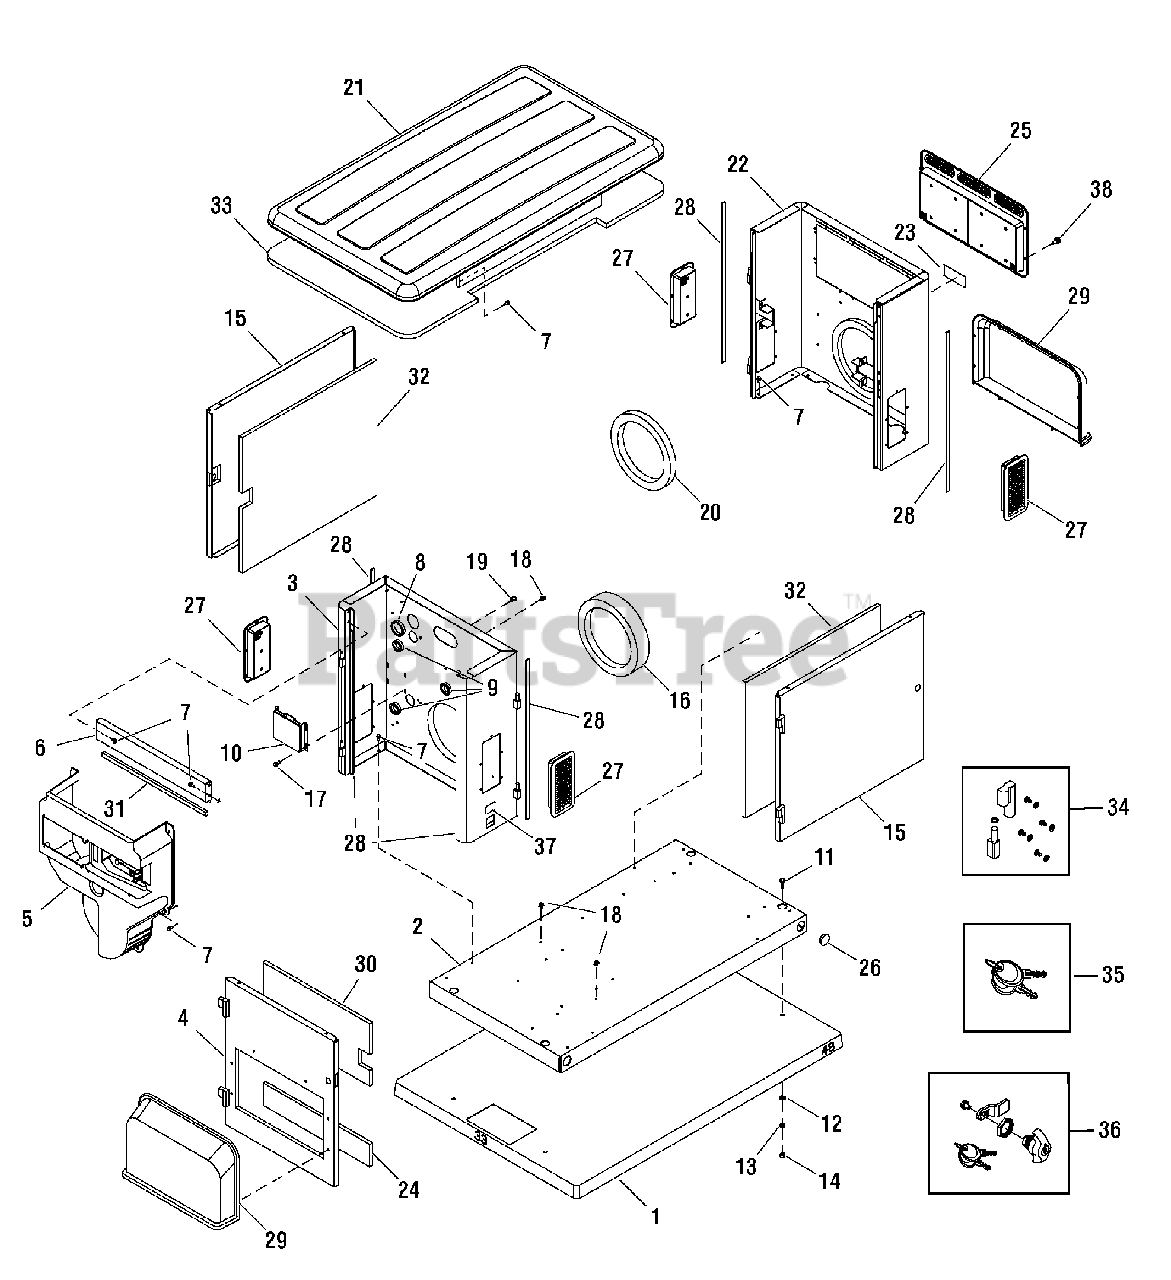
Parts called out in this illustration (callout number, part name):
1	PAD, Mounting w/ Holes
2	BASE, Mounting
3	BULKHEAD ASSEMBLY, Engine End
4	DOOR ASSEMBLY, Engine
5	DUCT ASSEMBLY, Engine
6	SUPPORT RAIL ASSEMBLY
7	BOLT
9	BUSHING, Snap, 1-1/2
10	REGULATOR, Voltage
11	* CAPSCREW, Hex Head, 3/8-16 x 1
12	* WASHER, Flat, 3/8-M10
13	* WASHER, Lock, 3/8
14	* NUT, 3/8-16
16	SEAL, Foam, Engine Air
18	MOUNT, Tie Wrap
20	SEAL, Foam, Alternator Inlet
22	BULKHEAD, Alternator
23	DECAL, Caution Hot Muffler
24	INSULATION, Engine Door, Bottom
25	ASSEMBLY, Vent, Exhaust
29	COVER, Air Intake, Engine
30	INSULATION, Engine Door, Top
32	INSULATION, Front / Rear Door
33	INSULATION, Roof
34	KIT, Door, Hinge
37	DOOR
37	WELDMENT
37	INSULATION
37	HINGES
37	DECALS
